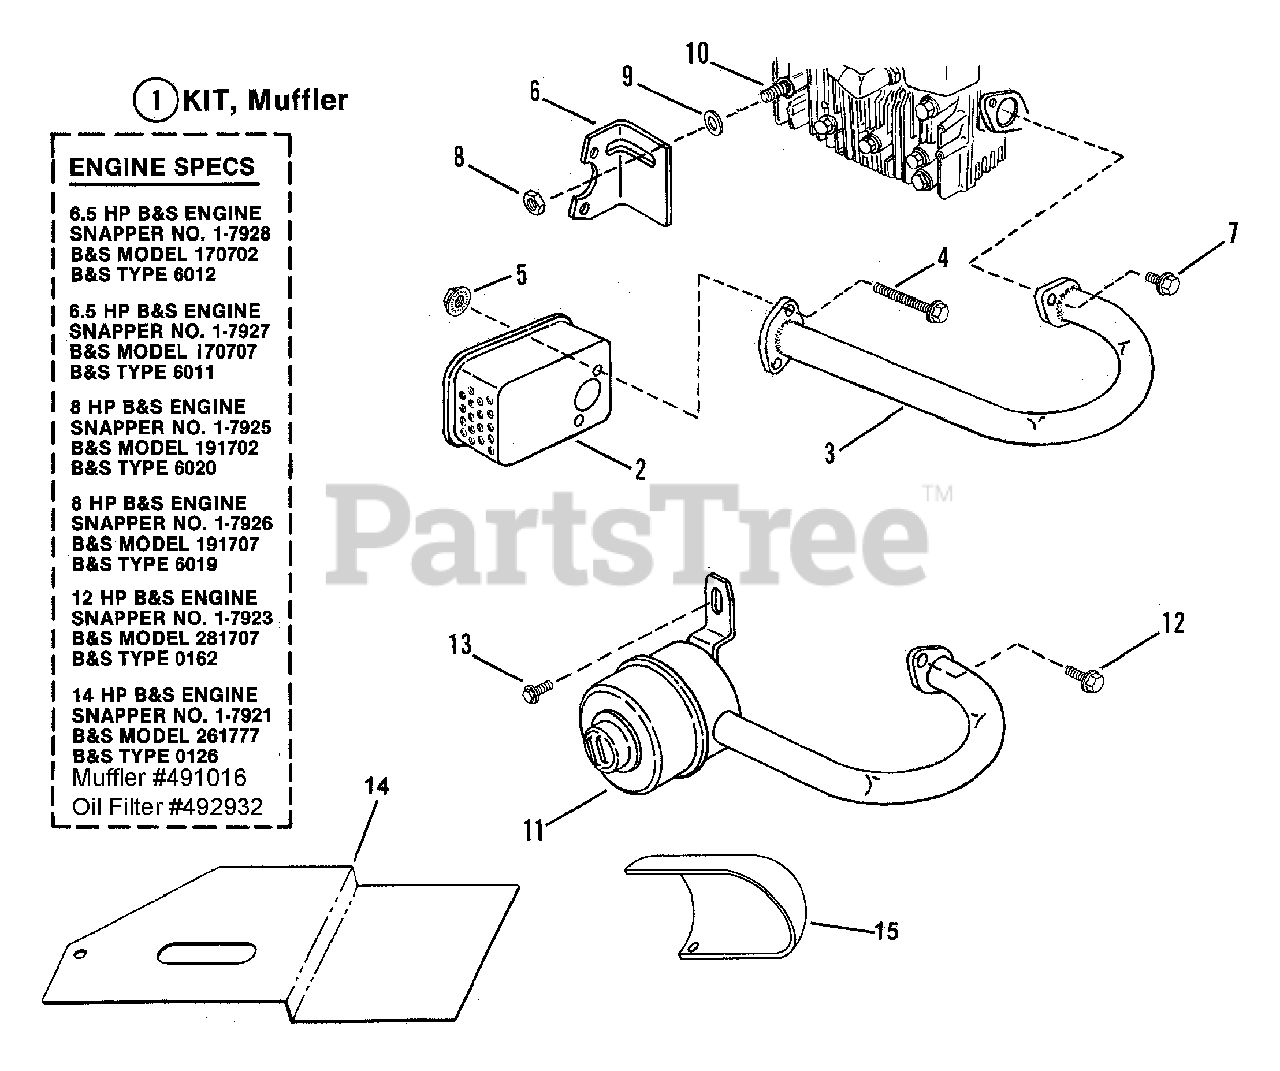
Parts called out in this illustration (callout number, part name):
1	KIT, Muffler
2	MUFFLER
3	TUBE, Exhaust
4	SCREW, 5/16-18 x 3" Hex Head Cap
5	NUT, 5/16-18 Hex Flange Lock
6	BRACKET, Muffler
7	SCREW, 1/4-20 x 5/8" Hex Head Cap
8	NUT, 5/16-18 Hex
9	WASHER, 21/64 Flat
10	STUD, Cylinder Head
11	MUFFLER
12	SCREW, 5/16-18 x 3/4" Hex Head Cap
13	SCREW, 1/4-20 x 3/4" Hex Head Cap
14	HEAT SHIELD, 14 HP Briggs Vanguard
15	DEFLECTOR, 14 HP Briggs Vanguard
